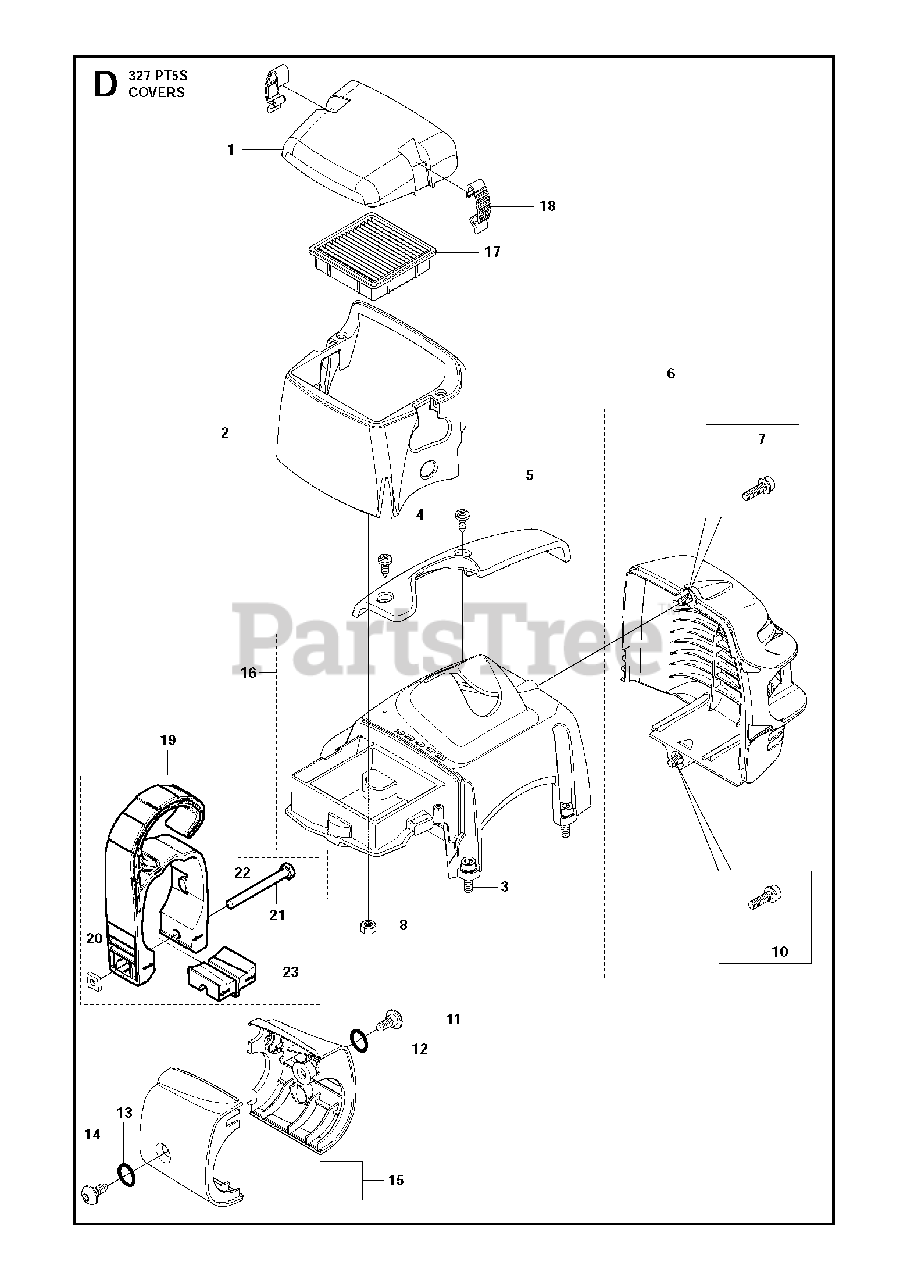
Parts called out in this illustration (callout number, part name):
1	FILTER COVER
3	SCREW IHSCFMO
5	ARM PROTECTION
6	HEAT PROTECTOR
7	SCREW IHSCFTO
10	SCREW IHSCFMO
11	SCREW MT5X11
12	O-RING 8X1.6
13	O-RING 8X1.6
14	SCREW MT5X11
16	CYLINDER COVER ASSY
20	NUT
21	SCREW M6X55
22	LOOP
23	SPACING BLOCK
